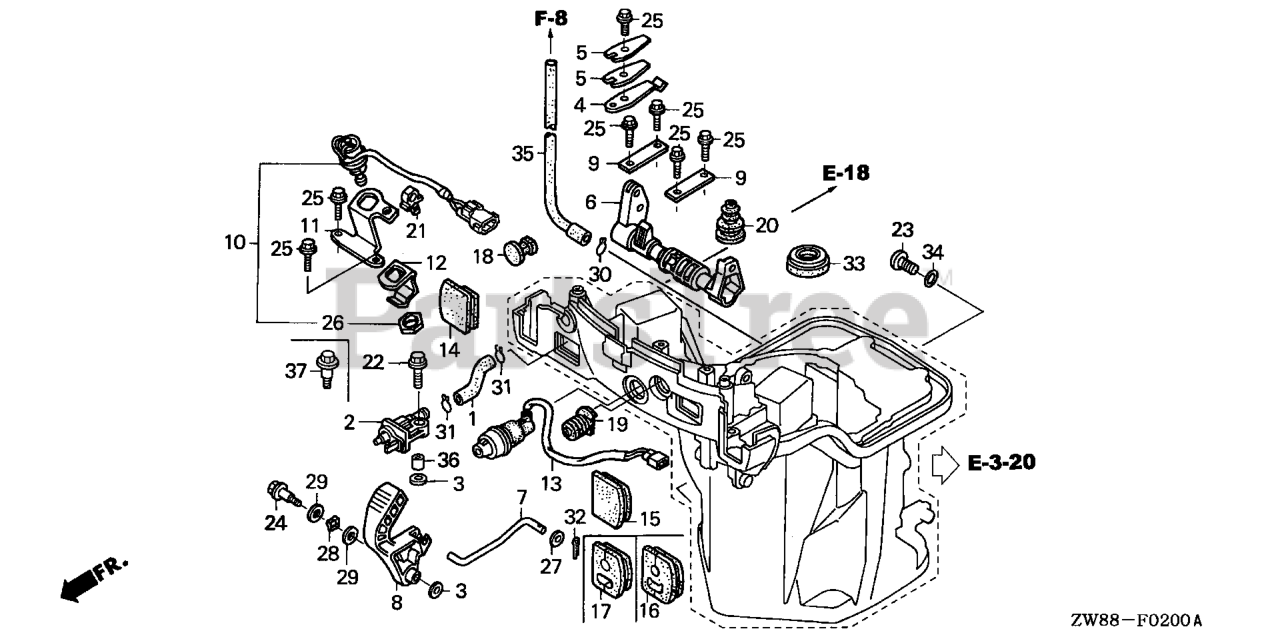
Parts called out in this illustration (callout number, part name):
1	TUBE A, FUEL
2	CONNECTOR ASSY., FUEL (B)
3	WASHER, PIVOT
4	SPRING, CLICK
5	SPRING, CLICK ASSIST
6	SHAFT, SHIFT
8	LEVER, SHIFT
9	PLATE, SHIFT SHAFT
10	SWITCH ASSY., NEUTRAL
10	SWITCH SET, NEUTRAL
11	BRACKET, NEUTRAL SWITCH
12	PLATE, NEUTRAL SWITCH (NOT AVAILABLE)
13	LAMP ASSY., INDICATOR
14	GROMMET A, OIL CASE
17	GROMMET B, OIL CASE
18	GROMMET F, OIL CASE
19	GROMMET D, OIL CASE
20	GROMMET E, OIL CASE
21	CLIP, BRAKE PIPE (A) (FOR NEUTRAL SWITCH)
22	BOLT, FLANGE (6X22) (CT200)
22	BOLT (6X22) (CT200)
23	BOLT, OIL CHECK
24	BOLT, REVERSE LOCK
25	BOLT, FLANGE (5X12) (CT200)
26	NUT, HEX. (20MM) Use up to Frame SN 1300359.
27	WASHER, PLAIN (5MM)
28	WASHER, WAVE (10MM)
29	WASHER, PLAIN (9MM)
30	CLIP, TUBE (B10)
31	CLIP, TUBE (B12)
32	PIN, SPLIT (2.0)
33	SEAL, WATER (13X28X7) (ENGINE NO.)
34	O-RING (5.5X1.5)
35	TUBE, WATER CHECK
36	COLLAR, DISTANCE (6MM)
37	BOLT, SPECIAL (6X22) (CT200)
